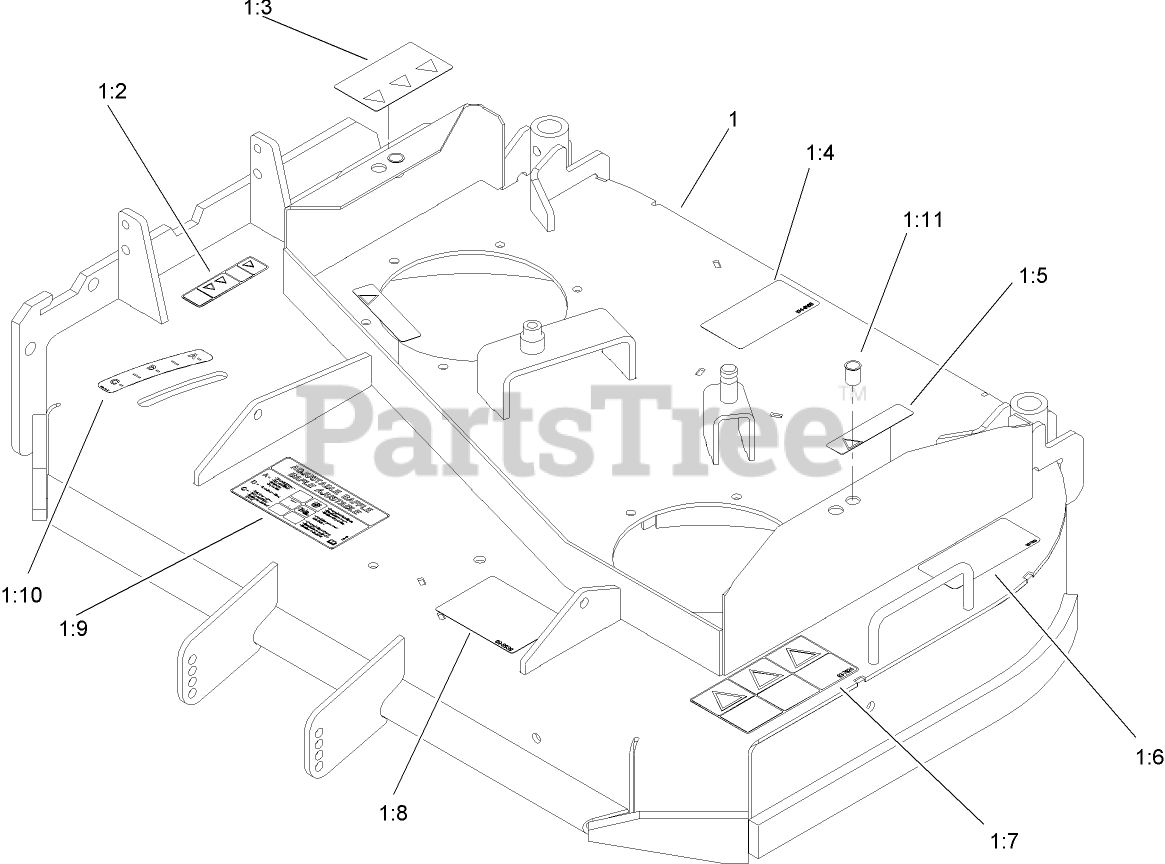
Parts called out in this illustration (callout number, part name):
1	91 CENTIMETER DECK ASM
1:2	DECAL-WARNING, DEFLECTOR
1:3	DECAL-DANGER
1:5	DECAL-WARNING
1:6	DECAL-TORQUE, BLADE BOLT
1:7	DECAL-DANGER
1:8	DECAL-ANTI SCALP
1:9	DECAL-ADJUSTMENT, BAFFLE
1:10	DECAL-SETTING, BAFFLE
1:11	INSERT-NUT
